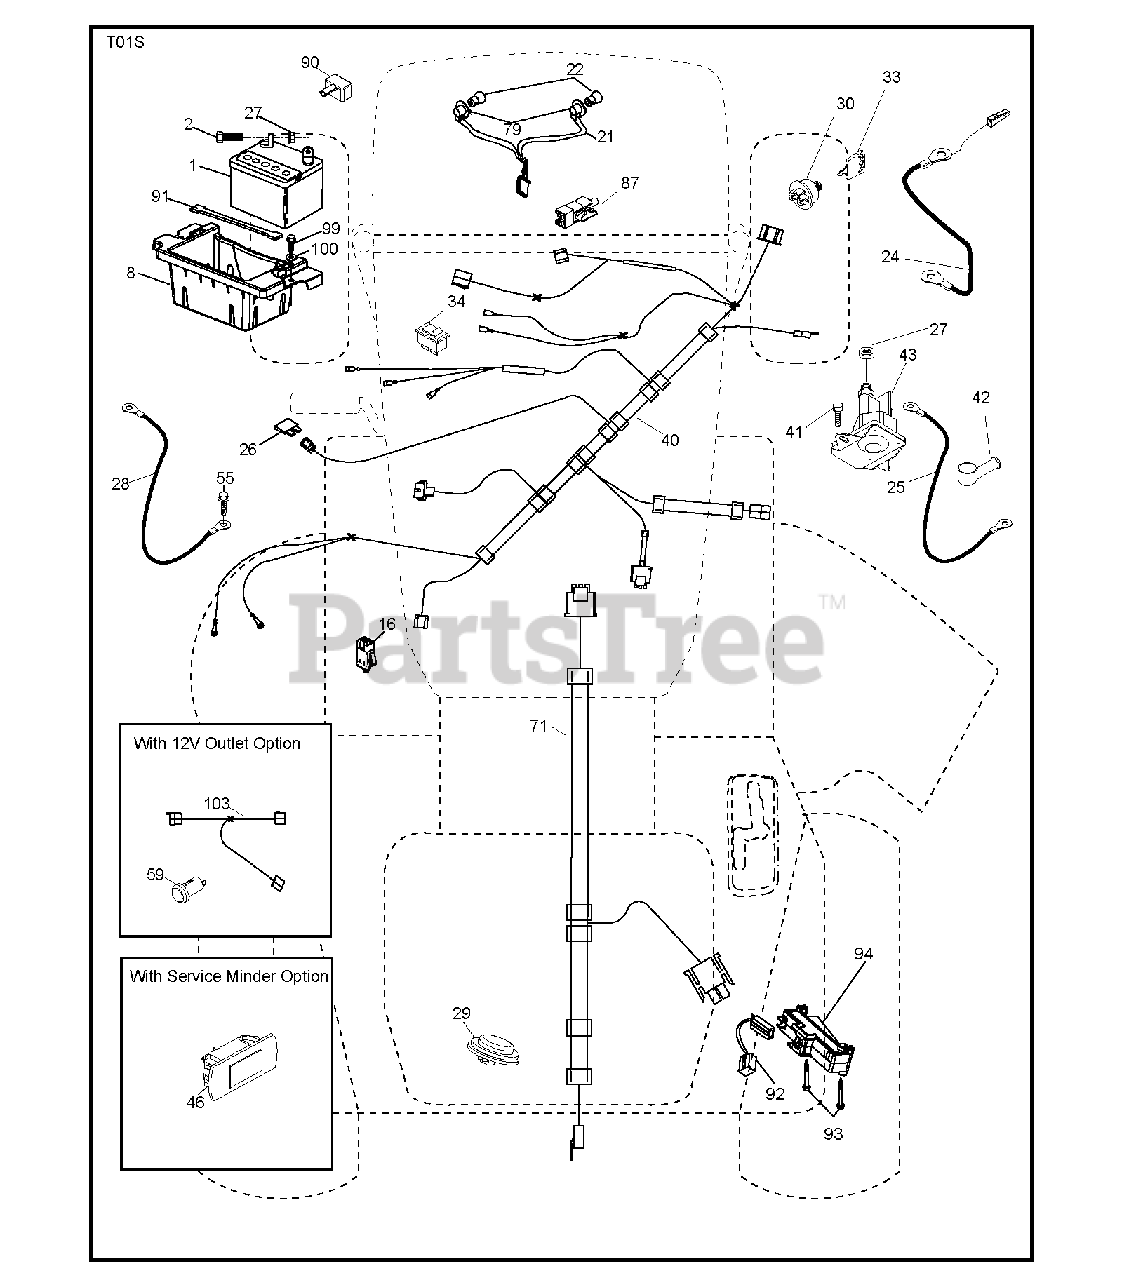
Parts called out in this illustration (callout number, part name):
1	Battery, Dry 30 Amp
2	BOLT.HEX.1/4.X.3/4.DICHROMATE
8	BOX.BATTERY.MOUNT.FRONT.LT
16	SWITCH INTERLOOK PUSH-IN
21	HARNESS ASSY LIGHT
24	CABLE.BATT.POS.WIRE.TG.DA SOL
25	CABLE.STARTER.6GA.BL/RED.14.
26	FUSE 20AMP
27	NUT
28	CABLE GROUND 6 GA 21" 90T BLK
29	SWITCH.SEAT.DELTA.OPC.
30	SWITCH.IGN.DELTA.W.LGH.ROS
33	KEY.CHAIN.BLISTER.PACK.GEN.USA
40	HARNESS IGN. DASH
41	SCREW
42	TERMINAL COVER
43	SOLENOID.W/BRASS.PLUNGER
46	RP GUAGE.SRVCMNDR.HRMTR.
55	SCREW 5/16"
71	HARNESS-CHASSIS SUB
79	BULB HOLDER ASM.
87	SWITCH.INTRLCK.CLUTCH.
90	COVER.TERMINAL.BATTERY
91	STRAP.BATTERY.MOUNT.FRONT(2 2)
92	HARNESS.PIGTAIL.CONSLE
93	SCREW.PLASTITE
94	MODULE.REVERSE.ROS
99	SCREW HEXWSHR 1/4-20X3/4
